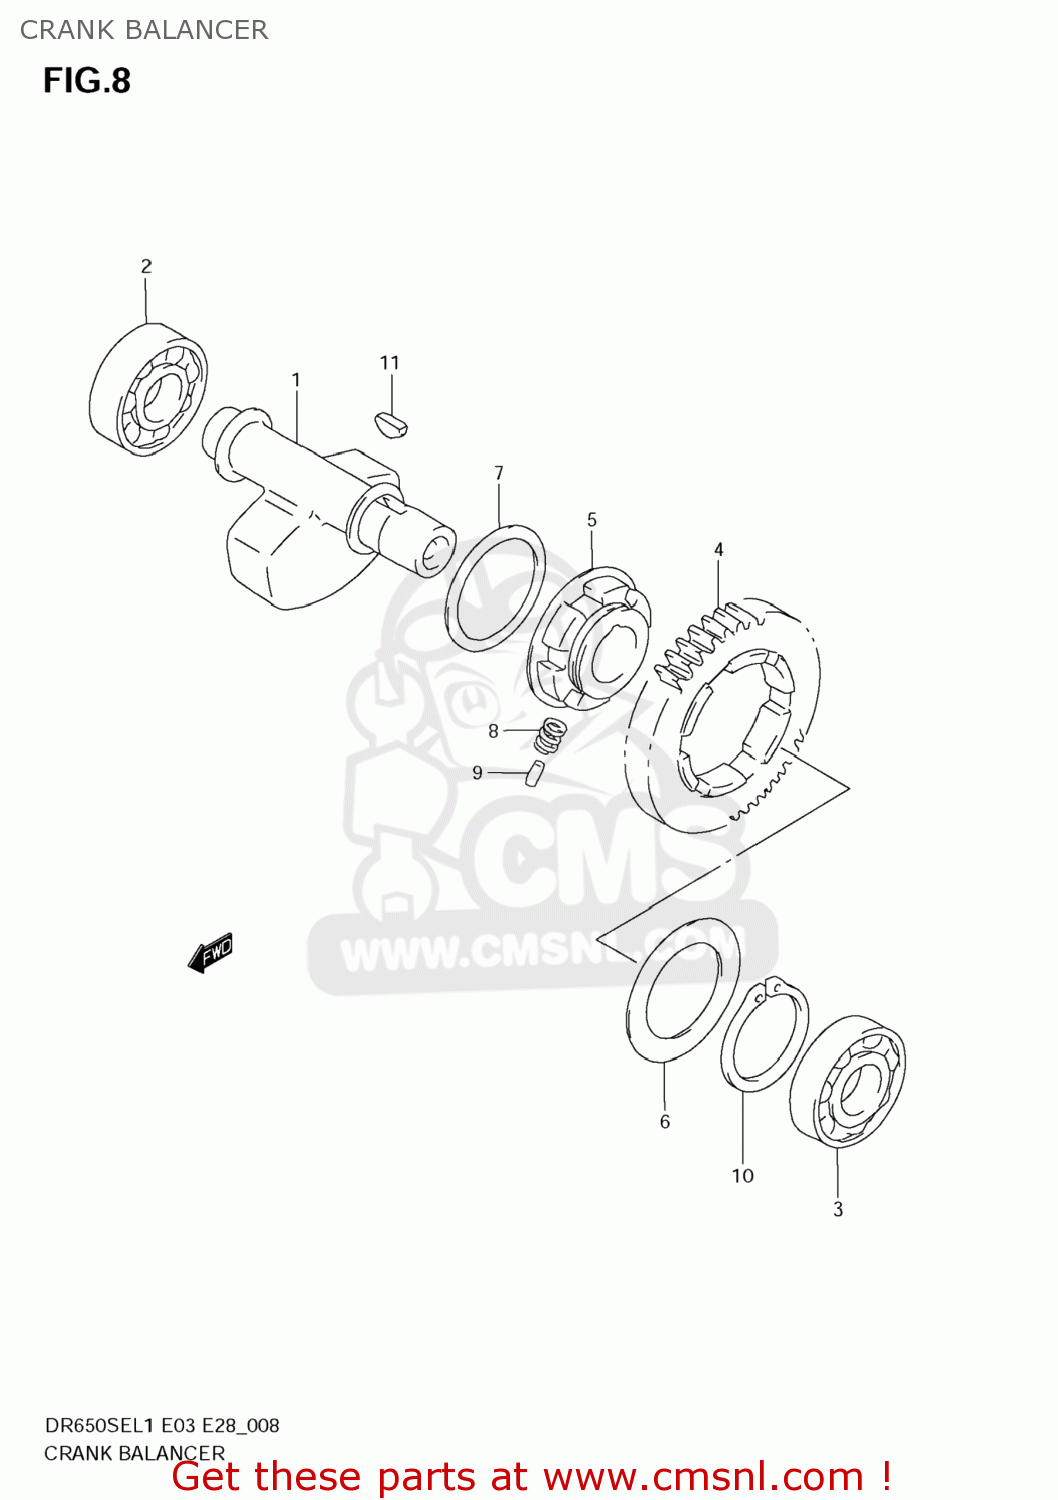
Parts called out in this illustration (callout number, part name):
1	BALANCER,CRANK
2	BEARING(22X56X16)
3	BEARING(20X47X14)
4	GEAR,CRANK BAL DRIVEN(NT:43)
5	RACE,CRK BAL DRIVEN GR INNER
6	WASHER
7	WASHER
8	SPRING
9	PIN(4.5X9.5)
10	CIRCLIP
11	KEY
